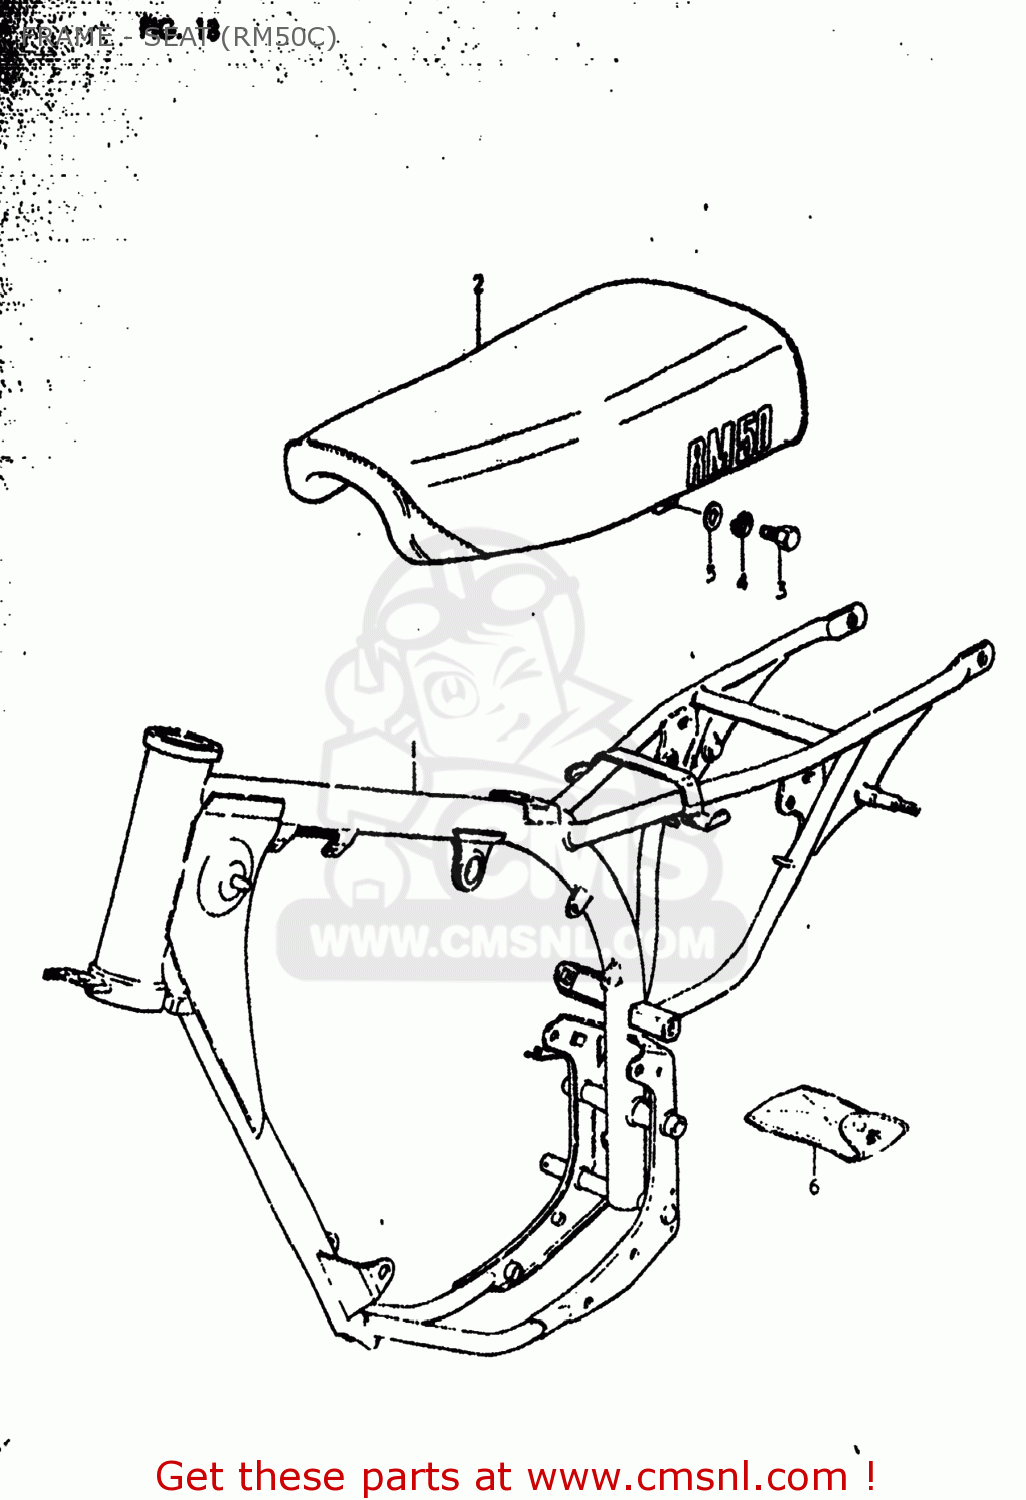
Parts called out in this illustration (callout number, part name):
1	FRAME
2	SEAT ASSEMBLY
3	BOLT
4	LOCK WASHER
5	WASHER
6	TOOL SET
